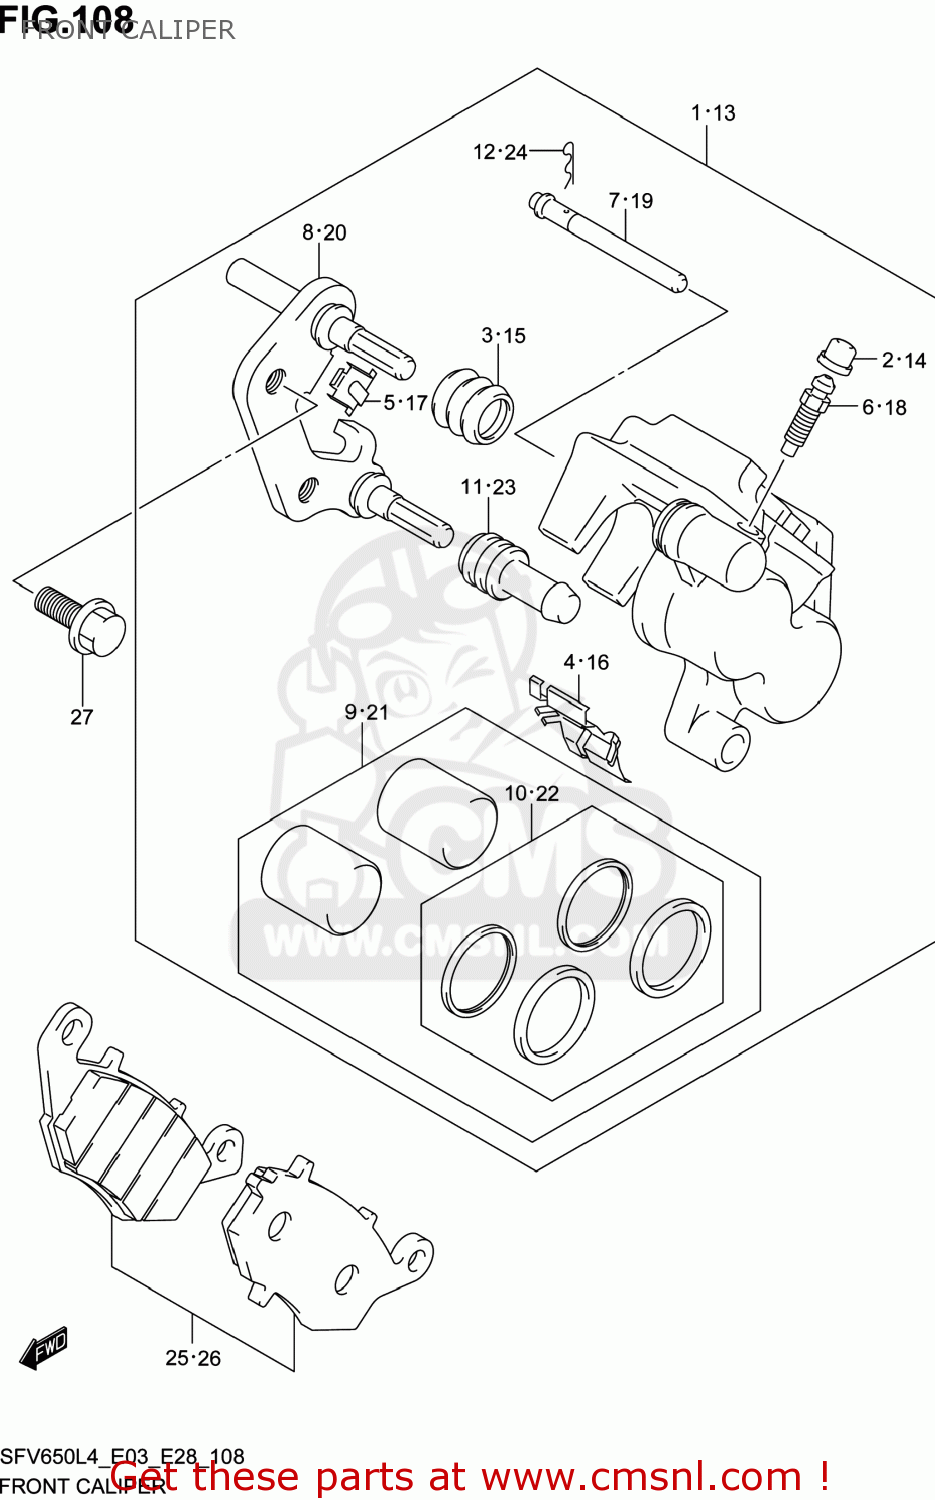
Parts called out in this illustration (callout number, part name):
1	CALIPER ASSY,FR,R
2	CAP,BLEEDER PLUG
3	BOOT,AXLE
4	SPRING,PAD,R
5	GUIDE,PAD
6	BLEEDER
7	PIN,PAD
8	CARRIER,CALIPER,R
9	PISTON SET
10	SEAL SET,PISTON
11	INSULATOR,AXLE
12	CLIP,PAD PIN
13	CALIPER ASSY,FR,L
14	CAP,BLEEDER PLUG
15	BOOT,AXLE
16	SPRING,PAD,L
17	GUIDE,PAD
18	BLEEDER
19	PIN,PAD
20	CARRIER,CALIPER,L
21	PISTON SET
22	SEAL SET,PISTON
23	INSULATOR,AXLE
24	CLIP,PAD PIN
25	PAD SET (NAS)
26	PAD SET (NAS)
27	BOLT
